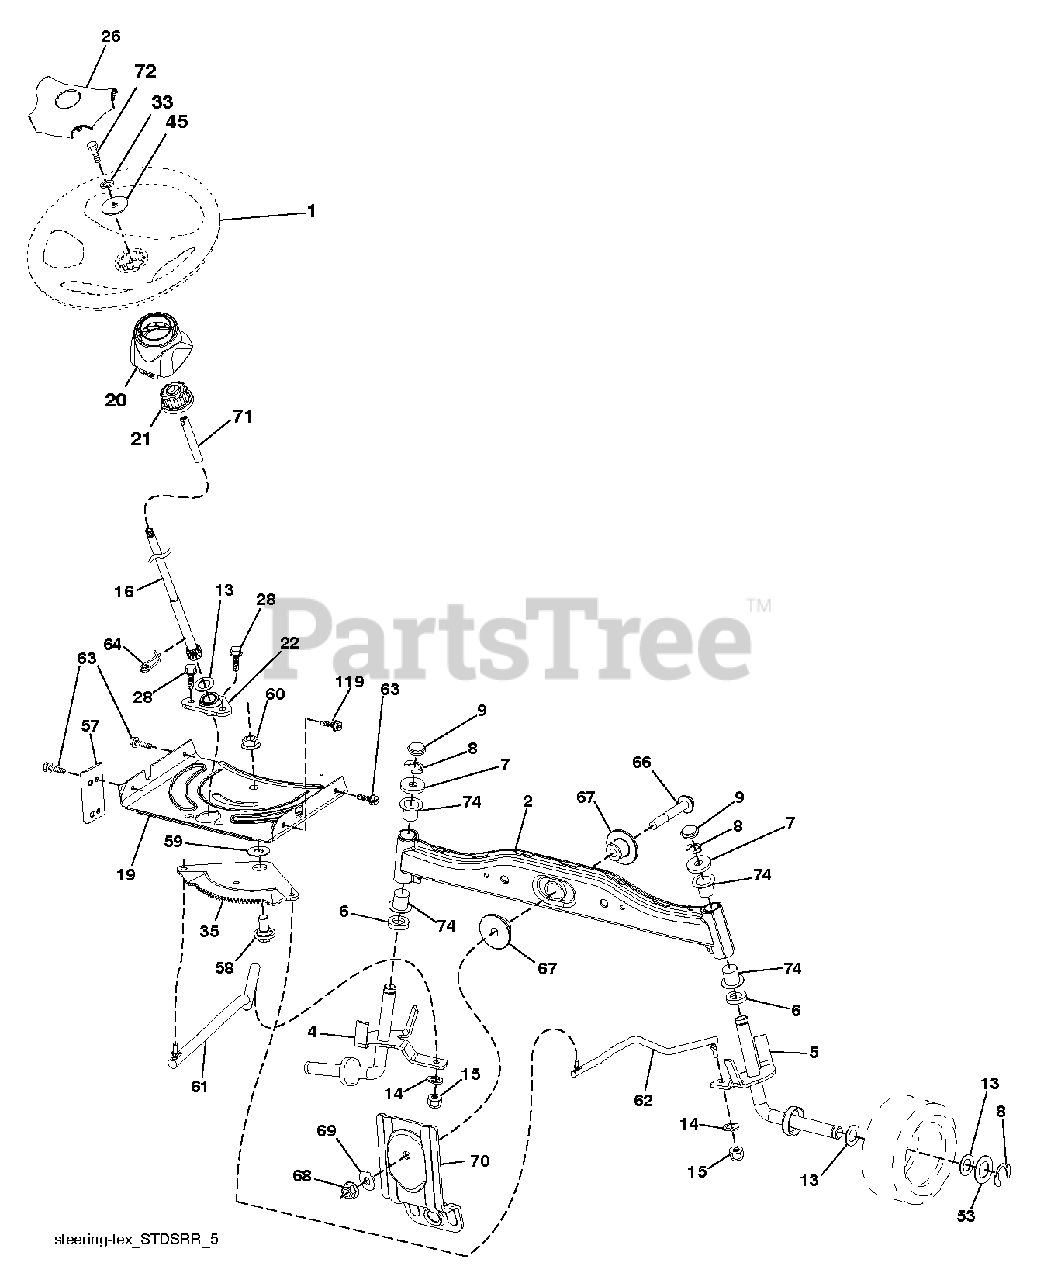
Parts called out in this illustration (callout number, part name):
1	WHEEL.STEERING.PREM.2.BLK
2	AXLE HALF ASM-WELDED
8	RING CLIP
9	CAP.SPINDLE
14	WASHER, LOCK 3/8
15	NUT CROWNLOCK 3/8-24
16	SHAFT.STEER.3/4.PLATED.TEX
19	PLATE.STEER.DDL.NLT/NG
20	BOOT.STEERING.PREDATOR.LT.BLAC
21	ADAPTER, WHEEL STNG..
22	STEERING.SUPT.LOWER.
26	INSERT.CAP.STRG.WH.BLACK
28	SCREW, 3/8-16X3/4
33	LOCKWASHER
35	GEAR.SECTOR.PLATE.DDL.
45	WASHER.11/32
53	WASHER.HARDENED
57	BRACKET.UPSTOP.TEX
58	BOLT.SHOULDER.SECTOR.P
59	WASHER.THURST.SECTOR.S
60	NUT FLANGE LOCK 5/8-11
61	DRAGLINK.LH.BALLSTUD.D
62	DRAGLINK.RH.BALLSTUD.D
63	SCREW
64	RETAINER.CLIP.SPRING.S
66	BOLT HEX FGHD 7/16-14 X 3 SERR
67	BUSHING.PM.FRONT AXLE
68	NUT.LOCK.FLANGE.7/16
69	WASHER.1.5X.505X.118
71	SHAFT.EXTEN.STRG.SPLINE
72	BOLT 5/16-18 X 4 W/PATCH
74	BRNG T
119	SHOULDER BOLT 5/16-18TT
